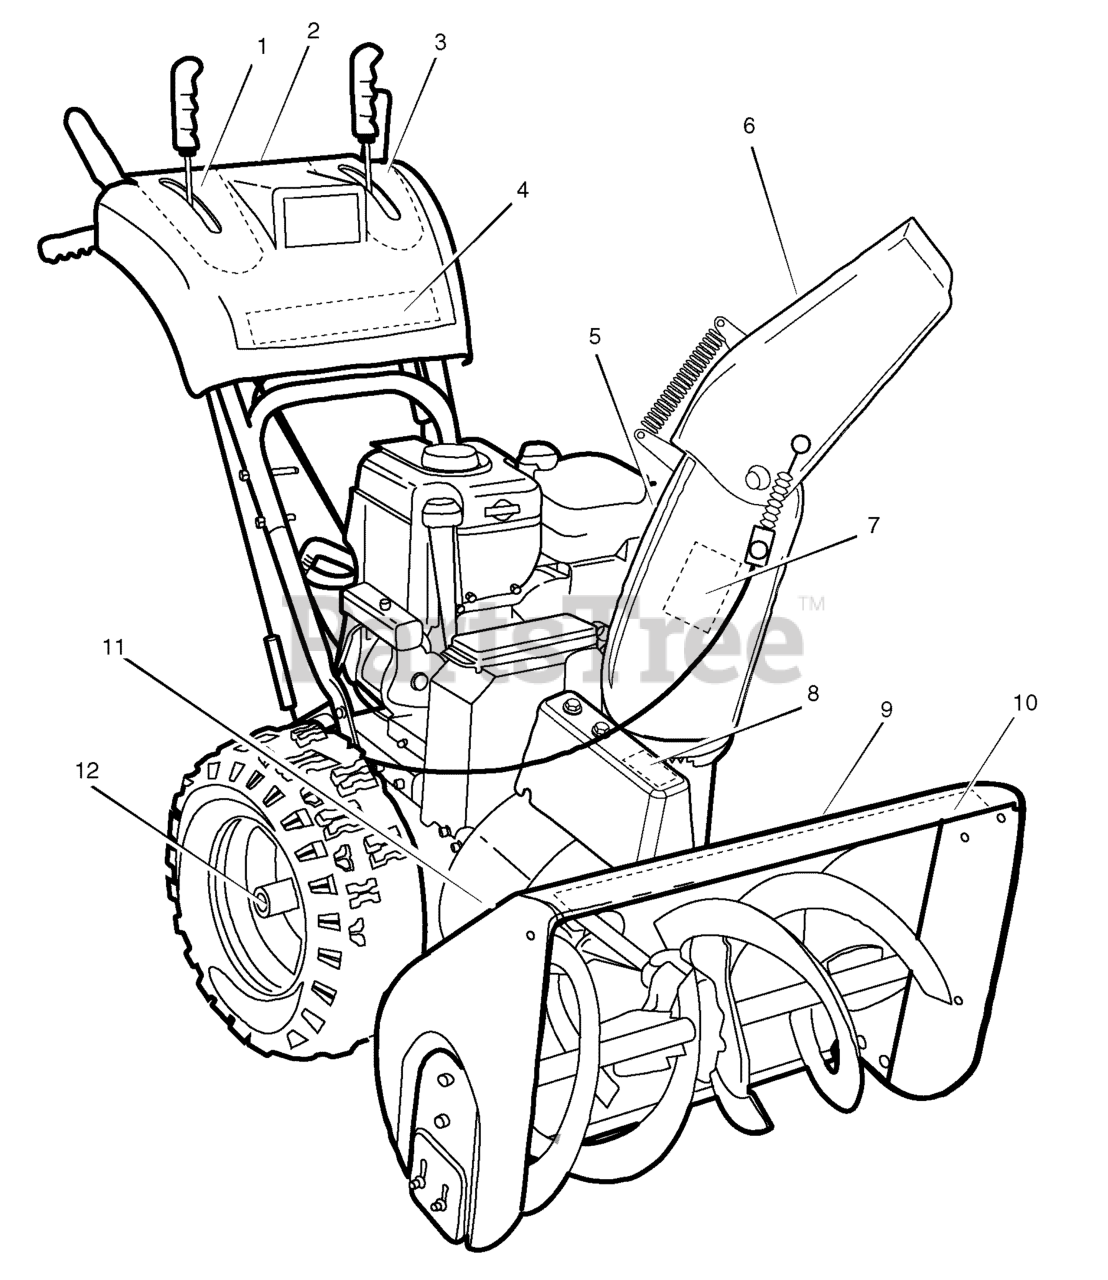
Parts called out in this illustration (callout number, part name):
1	DECAL, SPEED HYDRO P5 FR/EN
2	DECAL, SINGLE HAND CONTROL FR/EN
3	DECAL, REMOTE CHUTE ELECTRIC FR/EN
4	DECAL, YARD KING
5	DECAL, DANGER CHUTE FR/EN
6	DECAL, THROWN OBJECTS FR/EN
7	DECAL, HYDRO-SIDES OF CHUTE
8	DECAL, PINCH POINT ELECTRIC CHUTE
9	DECAL, CLEAN-CLEARBRUSH FR/EN
10	DECAL, YARDKING PERF EL. START 1650-33
11	DECAL, DANGER FOOT FR/EN
12	DECAL, WHEEL LOCK PICTORIAL
